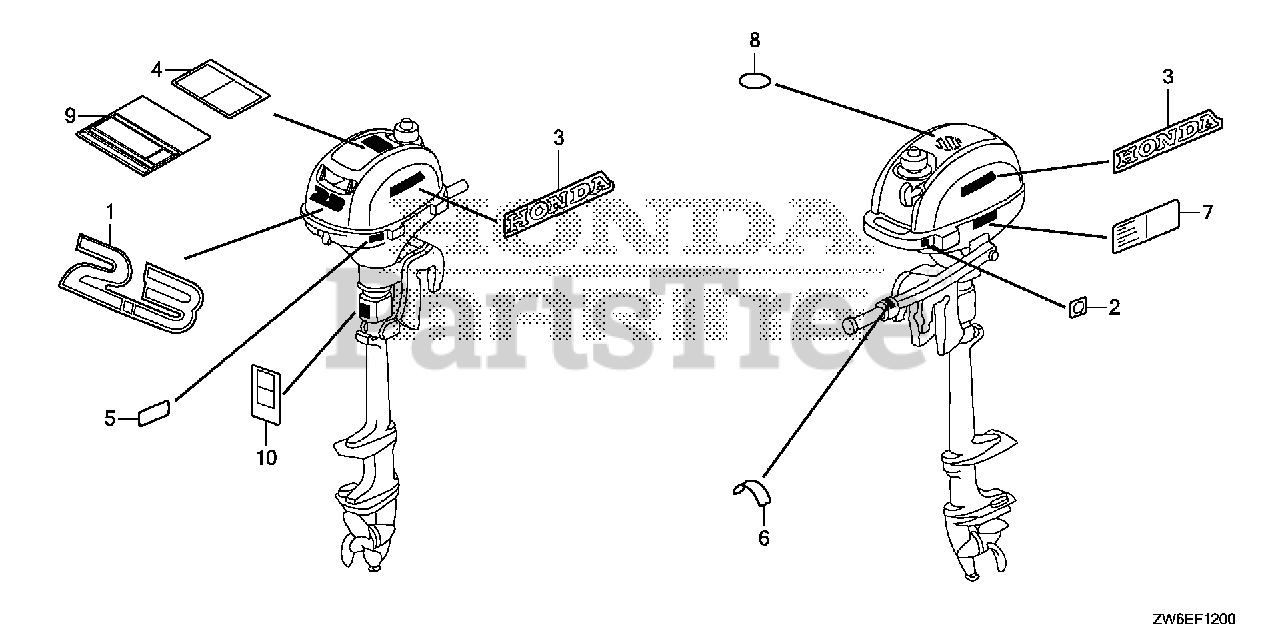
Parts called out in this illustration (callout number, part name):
1	MARK, RR. (2.3)
2	MARK, EMERGENCY SWITCH INDICATION (EU)
3	MARK, SIDE STRIPE (HONDA)
5	MARK, FUEL PETCOCK (E,F)
6	MARK, THROTTLE (GRIP TYPE)(E)
8	LABEL, RECOIL CAUTION
9	LABEL, OPERATOR CAUTION
10	MARK, EX. CAUTION (E)
